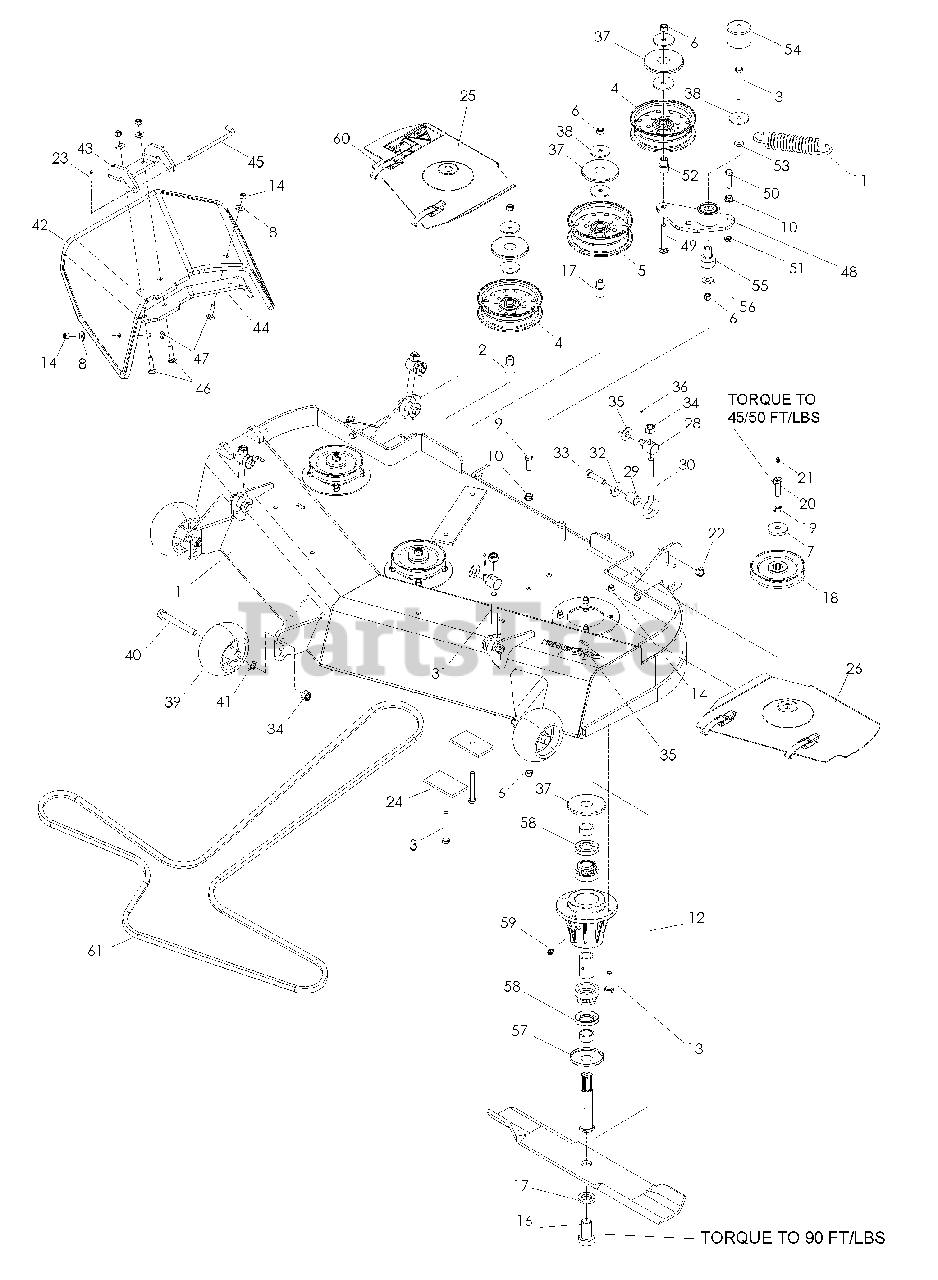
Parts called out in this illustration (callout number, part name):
1	DECK w/DECALS
2	BUSHING, IDLER
3	HCS 3/8-16 x 3
4	PULLEY, IDLER
5	PULLEY, IDLER
6	NUT 3/8-16 HEX NYLOC
7	WASHER, HEAVY
8	WASHER 5/16 STD FLT
9	HCS 3/8-16 x 1 1/4
10	NUT 3/8-16 WHIZLK
11	SPRING, EXTENSION
12	SPINDLE ASSEMBLY
13	HCS 5/16-18 x 1 1/4
14	NUT 5/16-18 HEX NYLOC
15	BLADE, 16 1/4
16	HCS 5/8-18 x 1 1/4
17	WASHER 5/8 SPLIT LOCK
19	LOCKWASHER 7/16
20	HCS 7/16-20 x 1 1/2 GR8
21	ZERK, STRAIGHT 1/4-28
22	NUT 7/16-14 HEX CTRLK GR A
23	PIN, COTTER 1/8 x 3/4
24	PAD
25	BELT SHIELD w/DECALS, RT
26	BELT SHIELD w/DECALS, LT
27	DECAL, TUNNEL RAM
31	EYE BOLT 1/2-13
32	WASHER 1/2 SPRING
33	HCS 7/16-14 x 1 3/4
34	NUT 1/2 -13 HEX NYLOC
35	WASHER 9/16 STD FLT
36	PIN, COTTER 1/8 x 1
37	DUST CAP, TOP
38	WASHER 3/8 SPECIAL
39	WHEEL, GAUGE
40	HBB 1/2-13 x 4
41	NUT 1/2-13
42	CHUTE, DISCHARGE
43	BRACKET, CHUTE
44	REINFORCEMENT, BRKT
45	PIN, CLEVIS
46	RHSNB 5/16-18 x 1 1/2
47	RHSNB 5/16-18 x 1 1/4
48	ARM, IDLER w/BEARINGS
49	RHSNB 3/8-16 x 2 3/4
50	HCS 3/8-16 x 1 1/2 GR8
51	NUT 3/8-16 HEX JAM
52	BUSHING, IDLER
53	WASHER 3/8 SAE FLT
54	CAP, VINYL
55	BEARING, PIVOT
56	WASHER 3/8 FLAT STD
57	DUST CAP, BOTTOM
58	SEAL, SHAFTL
59	GREASE POPPET
60	DRAW LATCH
61	BELT, DECK
